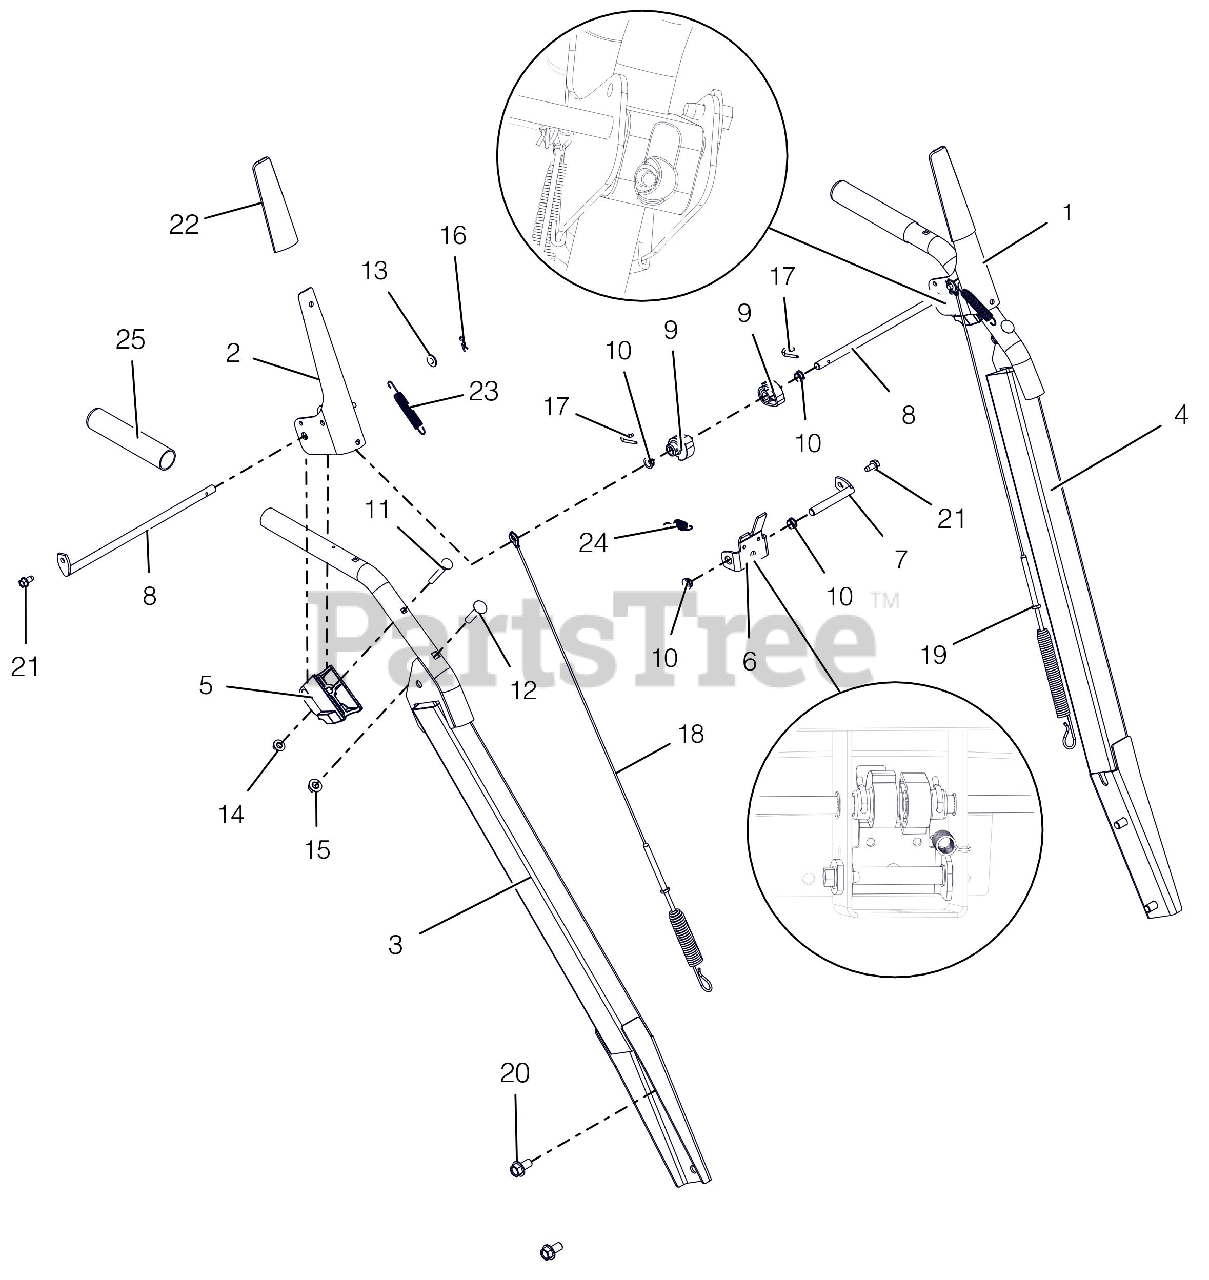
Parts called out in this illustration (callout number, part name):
1	LEVER, CLUTCH-LH
2	LEVER, CLUTCH-RH
3	HANDLEBAR, HEAVYDUTY-PRO-RH
4	HANDLEBAR, HEAVYDUTY-PRO LH
5	BLOCK, CLUTCH PADDLE
6	BRACKET, INTERLOCK ARM
7	ROD, PIVOT - INTERLOCK
8	ROD, PADDLE MOUNT - PRO
9	CAM, INTERLOCK
10	BUSHING, POLYLINER-.38 SNAPIN
11	BLT-RDHDXLSQNK .25-20X2.0 G5YZ
12	@BLT-RDHDSQNK .31-18X1.50 G5YZ
13	@WSHR-FL-STL.281X.62X.065 YWZC
14	@NUT-LK-CTR-FLG .25-20 YWZC
15	@NUT-LK-TOP-FLG .31-18 YWZC
16	PIN-HAIR INT .06X.18X.77
17	PIN, SPRING CLIP
18	CABLE, AUGER (DELUXE & PRO)
19	CABLE, UPPER TRACTION
20	BLT-SERHFWH .38-16X.75 YWZC
21	SCR-TAP .25-20X.50 HWH TR YWZ
22	SLEEVE, CLUTCH PADDLE-GRAY
23	SPRING, EXTENSION
24	SPRING-EXT .047X.438X1.45
25	GRIP,HANDLE-GRAY
